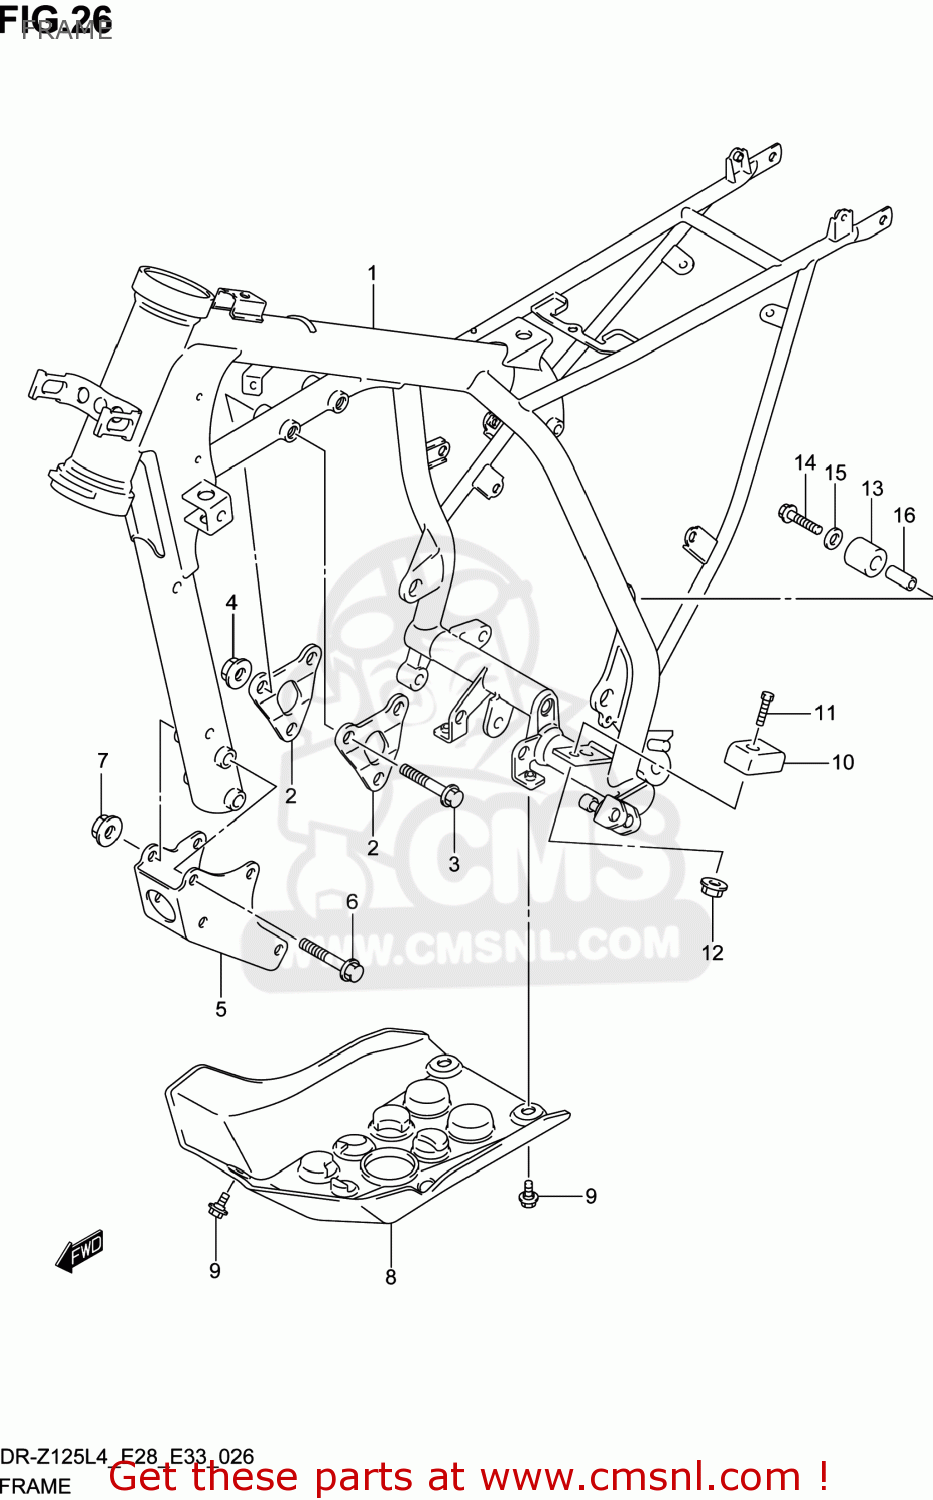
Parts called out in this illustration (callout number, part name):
1	FRAME(GRAY)
2	PLATE,ENG MTG UPR
3	BOLT(8X53)
4	NUT
5	PLATE,ENG MTG LWR
6	BOLT(8X65)
7	NUT
8	PROTECTOR,ENGINE
9	BOLT(6X12)
10	GUIDE,CH LENGTH CONTROL LWR
11	BOLT(6X16)
12	NUT
13	ROLLER,CHAIN CONTROL UPR
14	BOLT(8X38)
15	WASHER
16	SPACER(8.6X12.2X26.5)
